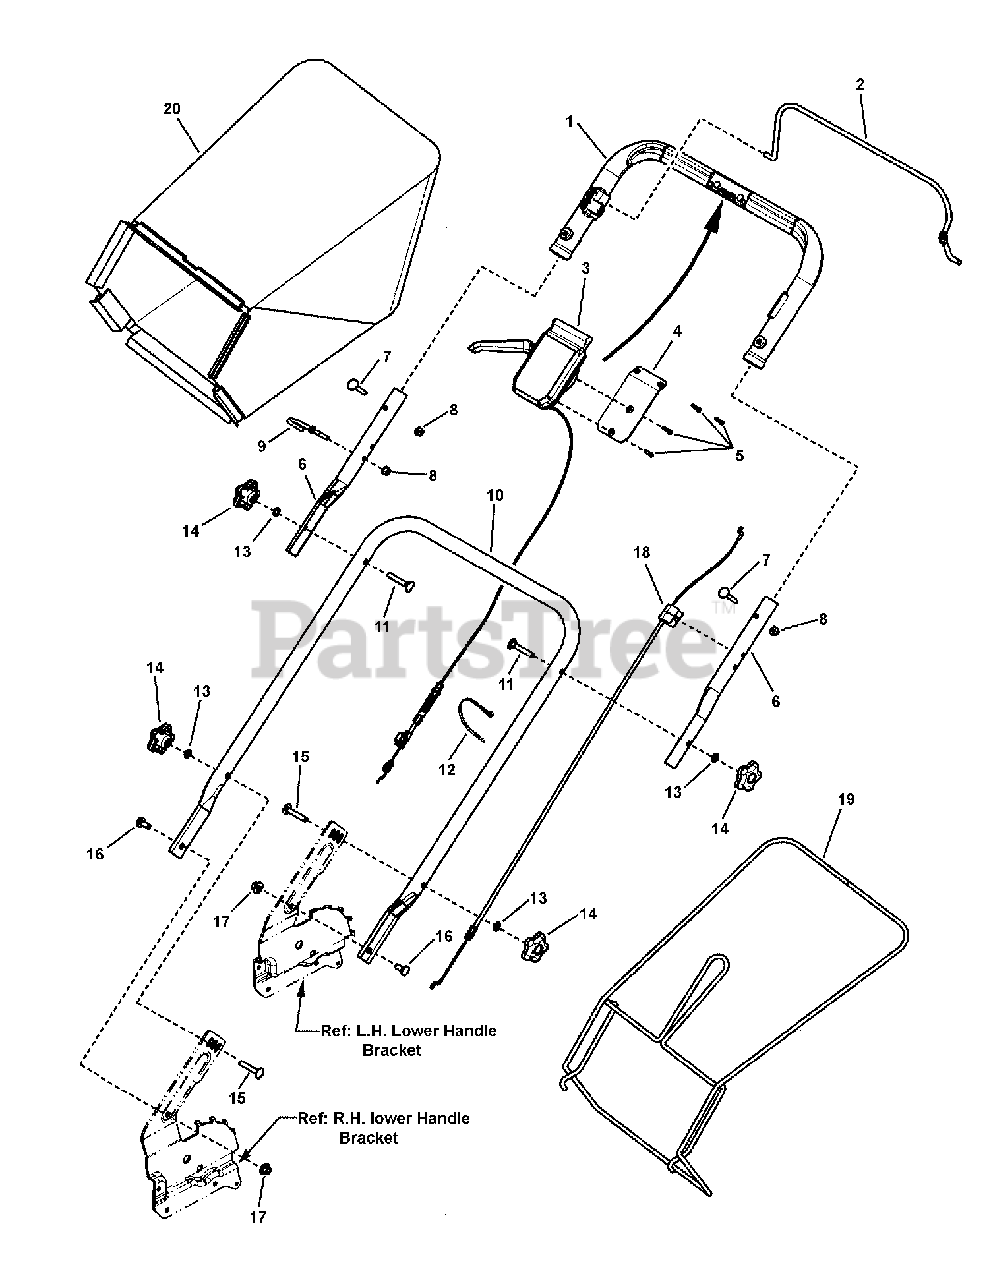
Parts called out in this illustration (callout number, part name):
1	HANDLE, Plastic Upper, WBM
2	BAIL, Plastic Handle, WBM
3	ASSEMBLY, Control Head, Variable Speed Front-Wheel-Drive
4	PLATE, Control Panel- Plastic Handle
5	SCREW, Pan Head, Thread Rolling
6	HANDLE, Connecting 21/22 WBM
7	BOLT, 1/4-20 x 1-3/4 Round Head Square Neck, GR 2
8	NUT, 1/4-20, Hex Flange Nyloc, YZ
9	GUIDE, Rope (1/4-20 threads)
10	HANDLE, Lower, 1", WBM
11	BOLT, 5/16-18 x 2 Curved Head Square Neck, GR 2
12	WIRE TIE,11 Inch Standard Black Nylon
13	WASHER, 5/16" Internal Tooth Lock
14	KNOB, Handle, (5/16-18 internal threads) 5-Prong
15	BOLT, 5/16-18 x 1-3/4" Round Head Square Neck Carriage
16	BOLT, 5/16-18 x 3/4" Round Head Short Square Neck Carriage, GR 5
17	NUT, 5/16-18 Large Head Center Lock, Black
18	CABLE, Bail, 22 WBM, (43.10" cable length)
19	BAG FRAME, Rear Discharge (weldment)
20	GRASS BAG, 22" Rear Discharge
